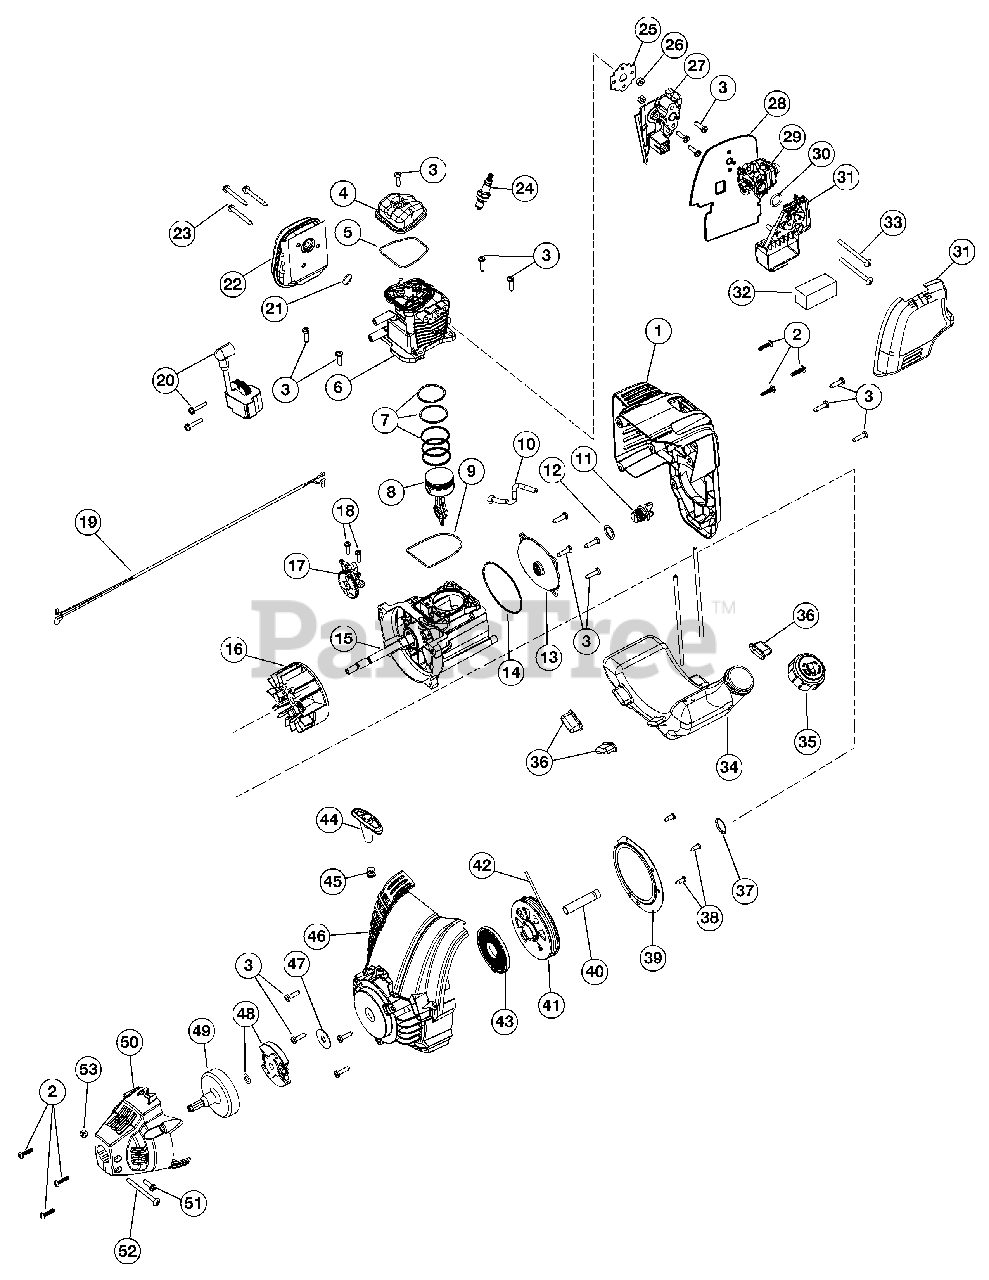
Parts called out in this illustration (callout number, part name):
1	Engine Cover Assembly (includes 2 & 3)
2	Cover Screw
3	Screw
4	Rocker Cover
5	Rocker Cover O-Ring
6	Cylinder Assembly (includes 3, 5 & 9)
7	Piston Ring Assembly
8	Piston Assembly (includes 7)
9	Cylinder O-Ring
10	Breather Hose
11	Oil Plug (includes 12)
12	Oil Plug O-Ring
13	Crankcase Cover
14	Crankcase Cover O-ring
15	Crankcase Assembly (includes 9, 10 & 14)
16	Flywheel Assembly
17	Cam Bracket Assembly (includes 18)
18	Cam Bracket Screw
19	Lead Wires
20	Module Assembly
21	Muffler Gasket
22	Muffler Assembly (includes 21 & 23)
23	Muffler Screw
24	Spark Plug
25	Insulator Gasket
26	Nut
28	Carburetor Gasket
29	Carburetor w/Primer
31	Air Cleaner Cover Assembly (includes 32)
32	Air Filter
33	Screw
34	Fuel Tank Assembly w/Fuel Lines (includes 35)
36	Fuel Tank Pads
37	Push Nut
38	Pressure Plate Screw
39	Pressure Plate (includes 38)
40	Spacer
41	Starter Assembly (includes 42)
43	Recoil Spring
44	Handle
46	Starter Housing Assembly (includes 3 & 37-45)
47	Washer
48	Clutch & Clutch Washer
49	Clutch Drum
50	Clutch Cover
51	Anti-Rotation Screw
52	Clamp Screw
53	Nut
